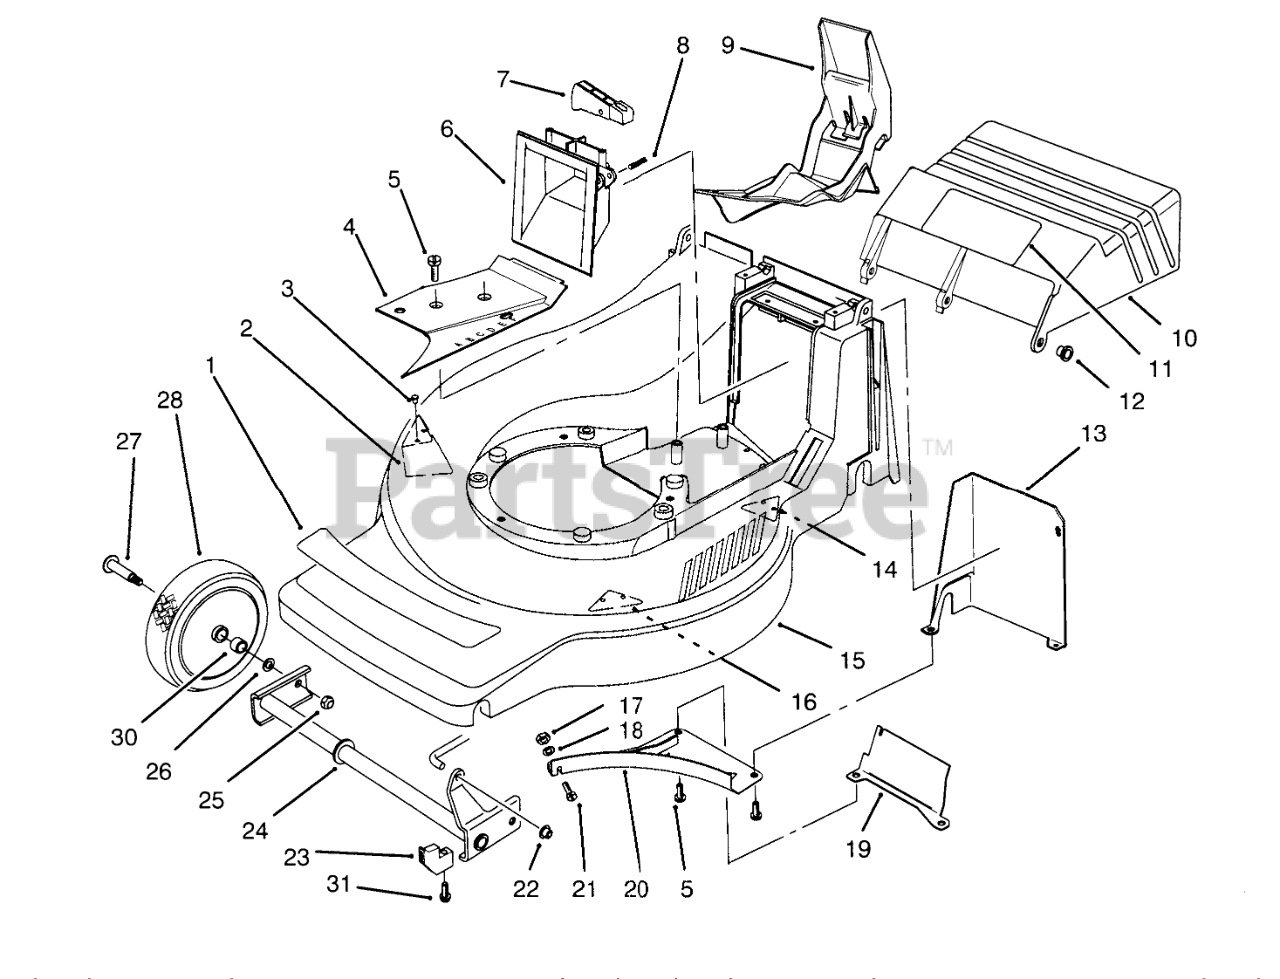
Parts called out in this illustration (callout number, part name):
1	DECAL - DECK
2	KICKER
3	SCREW-PPH
4	COVER - BELT
5	SCREW-RH
6	GRIP-LOWER
7	TRIGGER - HOC
8	PIN-SPIRAL
10	Door-Discharge
11	DECAL-DANGER
12	BUSHING-DOOR
13	COVER - SHIELD
14	KICKER
15	Housing-Deck (Incl. Ref.# 2, 3,14 & 16)
16	KICKER
17	NUT-LOCK, NI
18	WASHER-FLAT
19	BAFFLE-BAGGER, REAR
20	BAFFLE
21	SCREW-PPH
22	NUT-PUSH
23	RETAINER - AXLE
24	AXLE-FRONT
25	NUT-LOCK
26	WASHER
27	WHEEL BOLT
28	WHEEL-FRONT
30	BUSHING
31	SCREW-RETAINER
